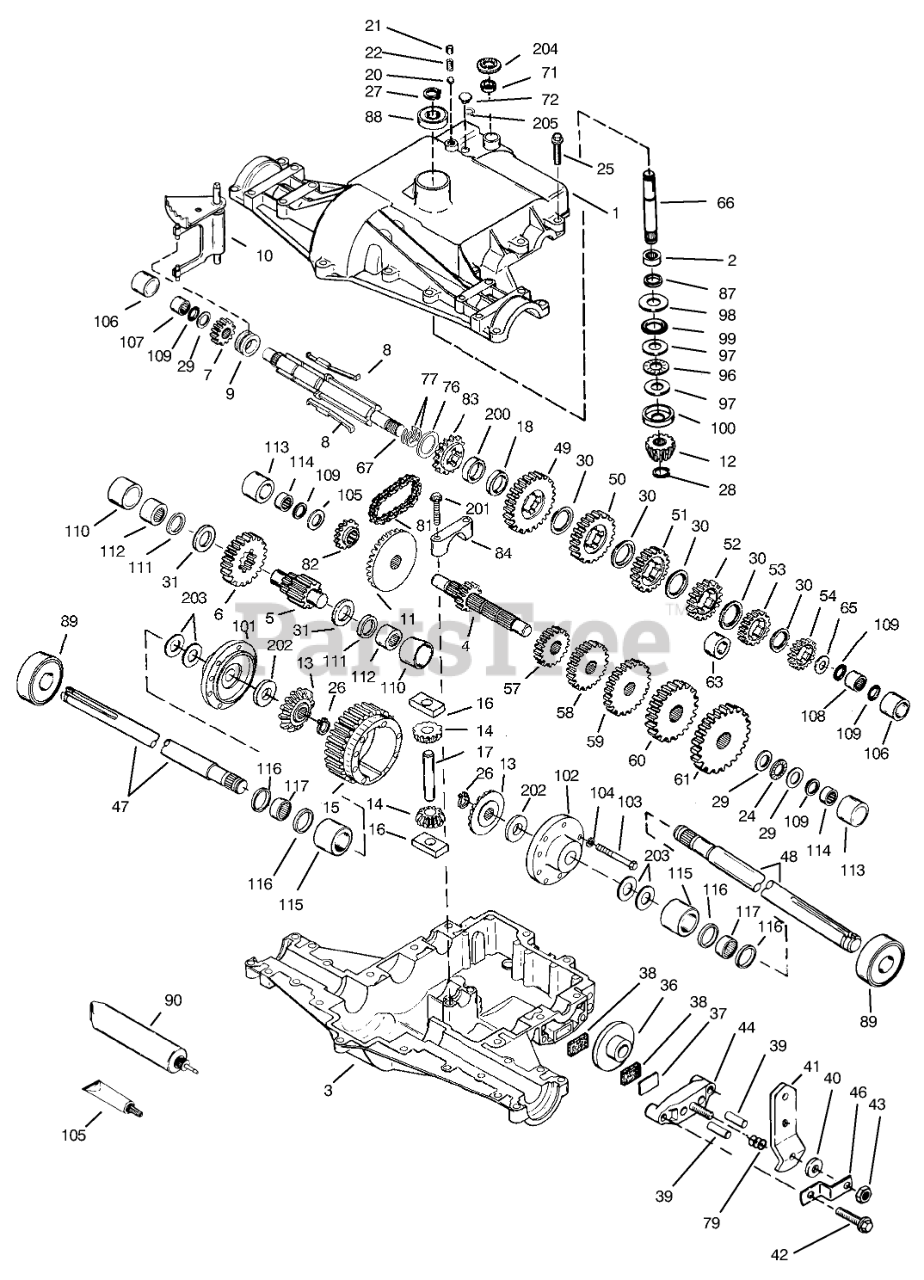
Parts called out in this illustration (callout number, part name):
1	Cover-Transaxle
2	Bearing-Needle
3	Case-Transaxle
4	Countershaft-Gear 9t
5	Shaft-Output
6	Gear-Output 35t
7	Gear-Spur 15t
8	Key-Shift
8	Key-Shift (820-024A Only)
9	Collar-Shift
9	Shift Collar
10	Fork-Shift
10	Fork-Shift (820-024A Only)
11	Gear-Bevel 33t
12	Pinion-Input 13t
13	Gear-Bevel
14	Pinion-Bevel
15	Gear-Ring
16	Biock-Drive
17	Pin-Drive
18	Spacer
20	Ball-Steel
21	Screw-Set
22	Spring
24	Bearing-Thrust
25	Screw 5/16-18x1 1/4
26	Ring-Snap
27	Ring-Snap
28	Ring-Retainer
29	Washer
30	Washer
31	Washer
37	Brake Pad Plate
38	Pad-Brake 2/Pkg
39	Dowel Pin
40	Washer
41	Lever-Brake
42	Ring Set (.020 O S)
43	Locknut
44	Nozzle-Carburetor
46	Bracket
47	Axle 12 9/16" Long
48	Axle 16 7/16" Long
49	Gear-Spur 41t
50	Gear-Spur 35t
51	Gear-Spur 30t
52	Gear Spur 25t
53	Gear Spur 22t
54	Gear Spur 19t
57	Gear Spur 15t
58	Gear Spur 20t
59	Gear Spur 25t
60	Gear Spur 28t
61	Gear Spur 30t
65	Washer
66	Shaft-Input
67	Shaft-Shifter/Brake
67	Shaft-Shifter/Brake (820-024A Only)
71	Cut Seal-Square
72	Plug-Threaded 5/16-18
76	Washer
77	Inverted Retaining Ring
79	Piston ASM (.020 O S)
81	Chain-Roller
82	Sprocket 10t
83	Sprocket (14 teeth)
84	Cap-Bearing
87	Seal Oil
88	Bearing-Ball
89	Bearing-Ball
90	Grease 32 Oz
96	Bearing-Thrust
97	Washer
98	Washer
99	O Ring
100	Washer-Cupped
101	Carrier-Differential
102	Carrier-Differential
103	Screw-Hex Hd.
104	Lockwasher
105	Washer
106	Sleeve
107	Bearing-Needle
108	Bearing-Needle
109	O Ring
110	Sleeve
111	Ring-Square Cut
112	Bearing-Needle
113	Sleeve
114	Bearing-Needle
115	Sleeve
116	Ring-Square Cut
117	Bearing-Needle
150	Gasket Eliminator
200	Spacer
201	Ring Set (.020 O S)
202	Washer
203	Washer
204	Pushnut
205	O Ring
